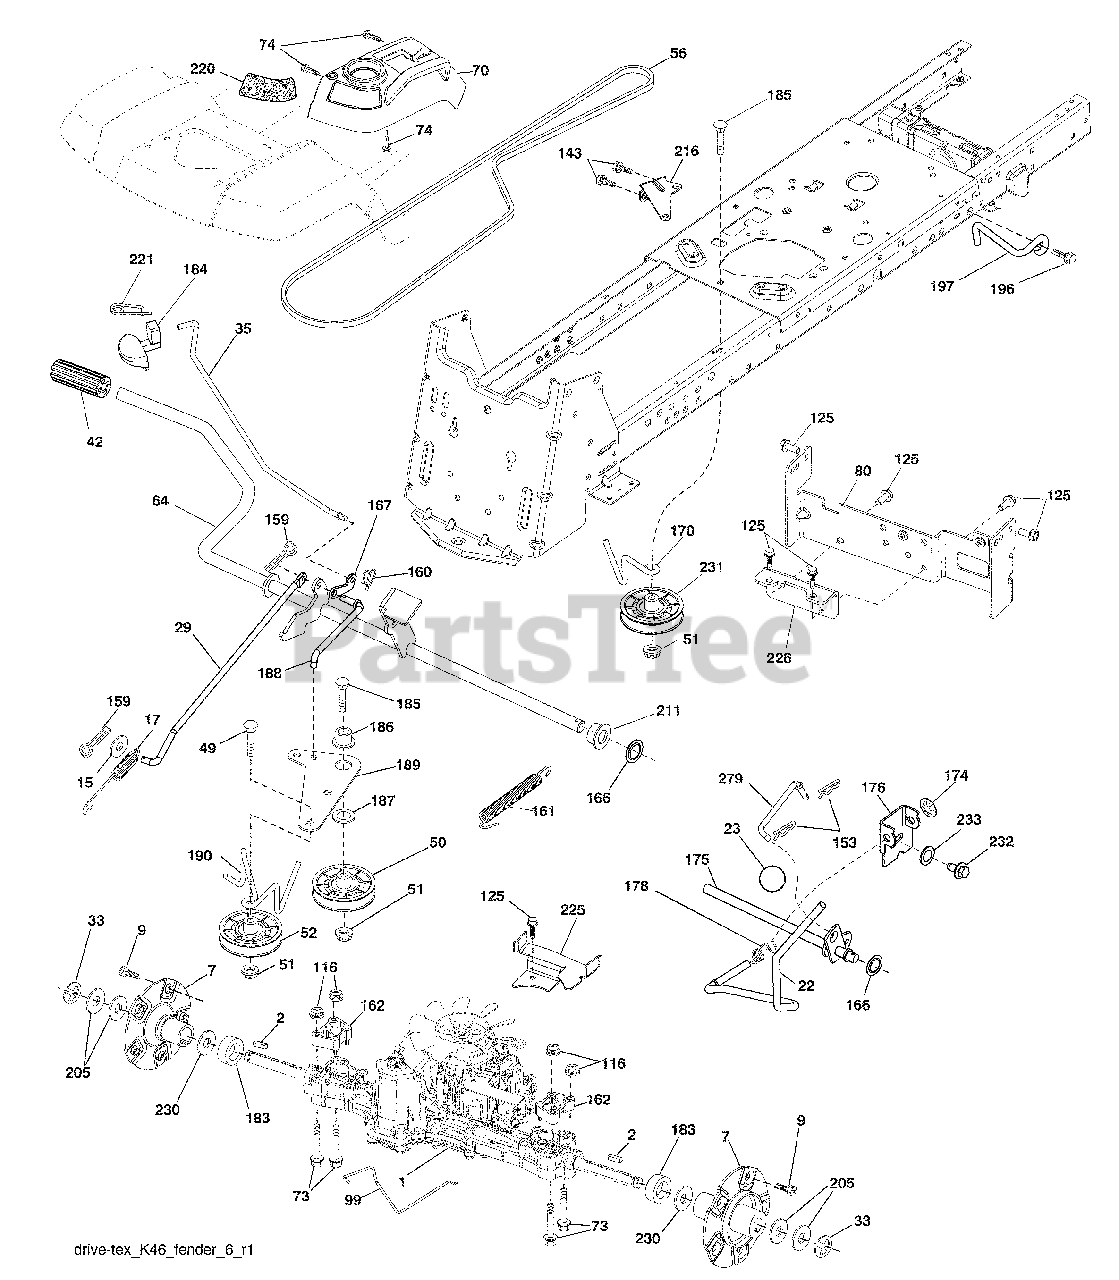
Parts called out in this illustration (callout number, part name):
1	Transaxle, TUFFTORQ K46 AW
7	Hub Asm. Wheel Rear 22" TX GT .06
9	Bolt Hub Wheel Rear
15	Washer 13/32 x 13/16 x 16 Ga.
17	Spring Brake
29	Rod, Brake
35	Rod Brake Park
42	Cover Foot Pedal
50	Pulley Idler Flat
51	Lock Nut 3/8-16
52	Idler V-Groove 910" Offset
56	V-Belt Drive
64	Shaft Asm. Pedal Brake Control
70	Console Asm.
73	Bolt Hex Flghd 5/16-18 x 3.75
74	Screw 1/4 x 1/2
80	Strap Torque
99	Rod Bypass
116	Nut Lock Hex Flange 5/16-18
125	Screw 5/16-18 x 3/4
143	Screw 5/16-18 x 1/2
153	Retainer Spring
159	Pin Cotter 1/8 x 3/4
160	Retainer Clip
161	Spring Return Clutch
162	Spacer Transaxle 18 and 22
166	Nut Push
167	Latch Brake Parking
170	Keeper Belt Centerspan
175	Shaft Asm Shift
176	Arm Clevis Rod Shift
178	Spring Shift
183	Spacer Split
184	Handle Parking Brake
185	Bolt Rdhd Sqnk 3/8-16 x 2-3/4 Gr. 5
186	Spacer Retainer
187	Washer
188	Link Clutch Ground Drive
189	Bellcrank Ground Drive
190	Keeper Bellcrank Ground Drive
196	Screw 3/8-16 x 1
197	Link Clutch Anti-Rotation
211	Bushing Brake Shaft
216	Bracket Pulley Idler
220	Reflector RH
221	Retainer Spring Clip Handle
225	Keeper Belt Trans.
226	Bracket Mount Torque
230	Washer Hardened
231	Idler V-Groove 1.688" Offset
232	Bolt 7/16-14 x 1 Gr. 5
233	Washer Serrated
279	Link Shift
